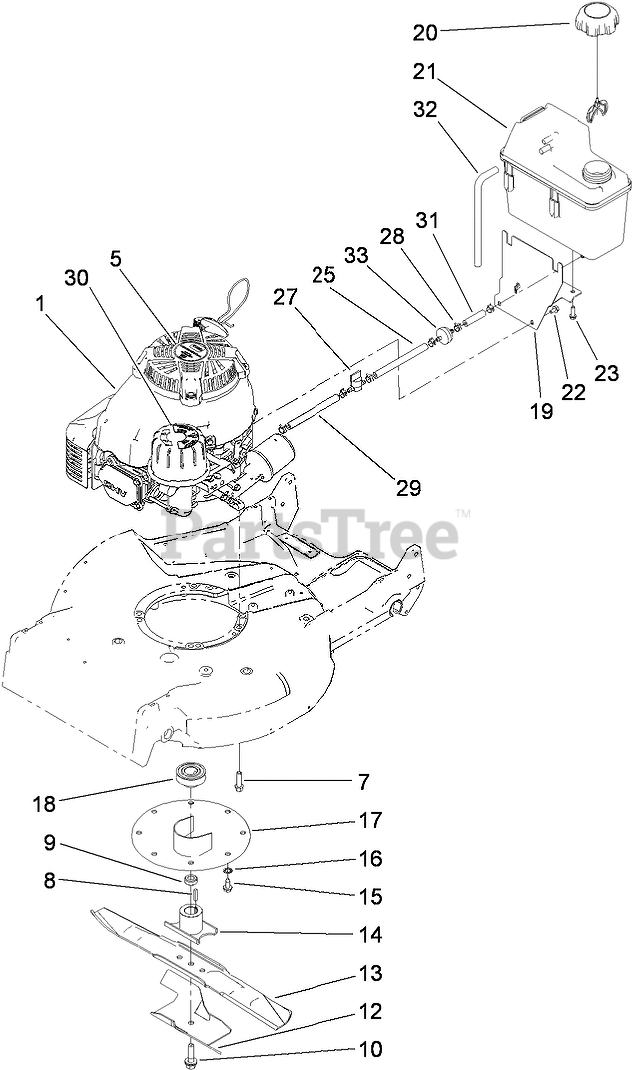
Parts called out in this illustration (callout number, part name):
1	ENGINE-KAWASAKI, FJ180V-AM08-M
5	DECAL
7	SCREW-TAPTITE
8	KEY-SQUARE
9	Spacer-Retainer, Blade
10	BOLT-BLADE
12	STIFFENER-BLADE
13	BLADE-21 INCH
14	RETAINER-BLADE
15	SCREW-HWHTF
16	WASHER-LOCK, INTERNAL
17	PROTECTOR-CRANKSHAFT
18	PULLEY-DRIVER
19	MOUNT-TANK
20	CAP-RATCHET, TETHERED
21	TANK-FUEL
22	SCREW-HWH
23	SCREW-HWH
25	HOSE-FUEL
27	VALVE-FUEL
28	CLAMP-HOSE
29	HOSE-FUEL
31	HOSE-FUEL
32	HOSE-VENT, CANISTER
33	FILTER-FUEL
